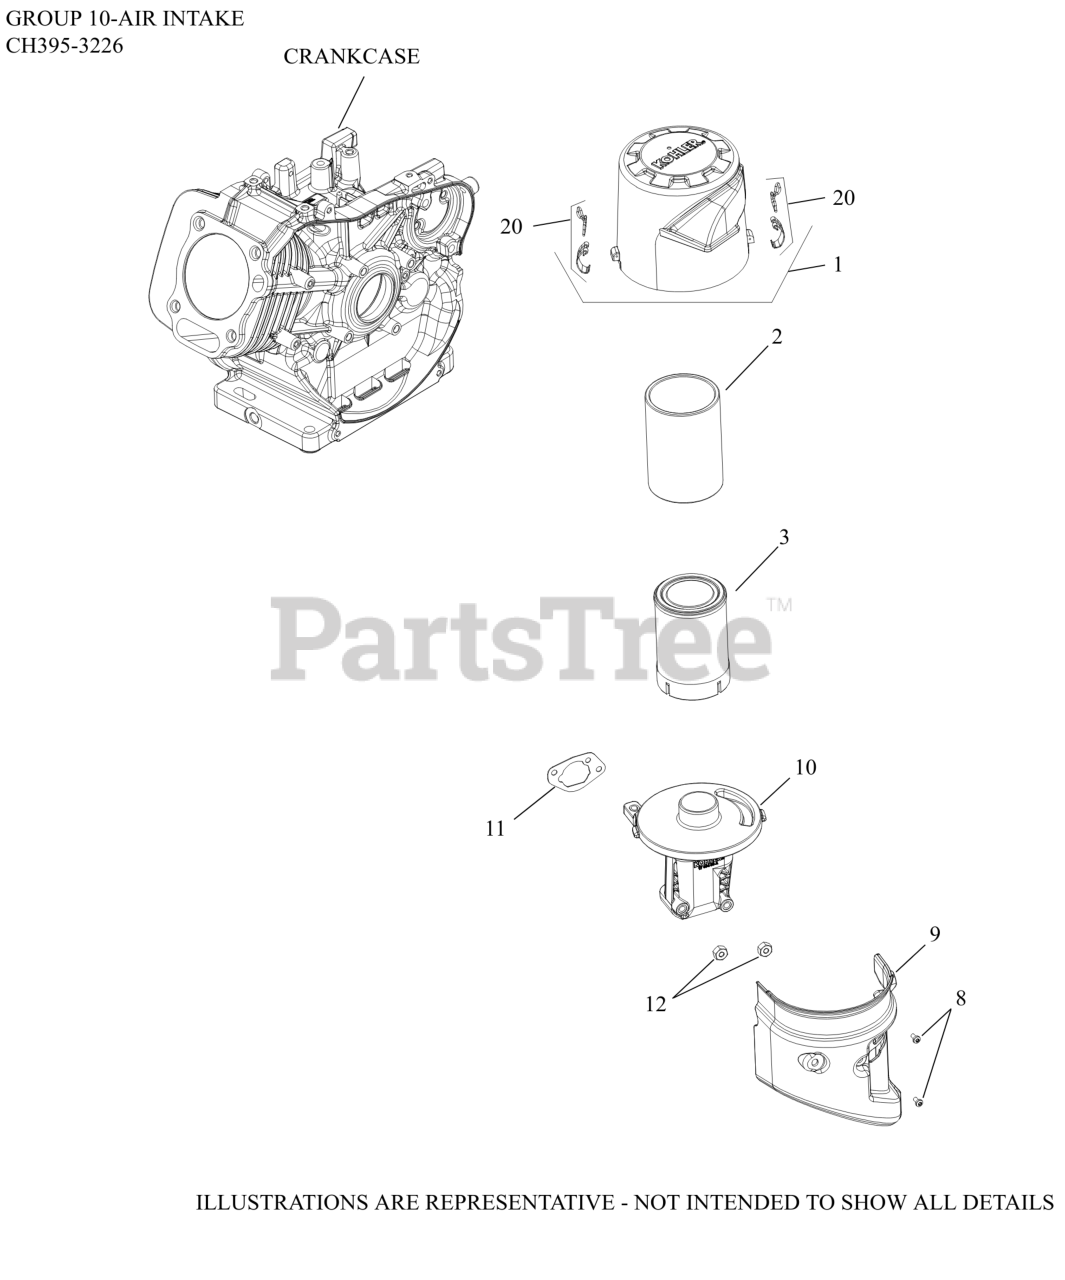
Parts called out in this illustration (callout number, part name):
1	COVER, AIR CLEANR ASSEMBLY
2	ELEMENT, PRE-CLEANER
3	ELEMENT, AIR FILTER
8	SCREW,COVR TO BLWR HOUSING
9	COVER, A/C BASE CH395
10	AIR CLEANER BASE ASSY
11	GASKET, AIR CLEANER
12	NUT, HEX (M6 THREAD, M8 BODY)
20	KIT, LATCH CLIP
